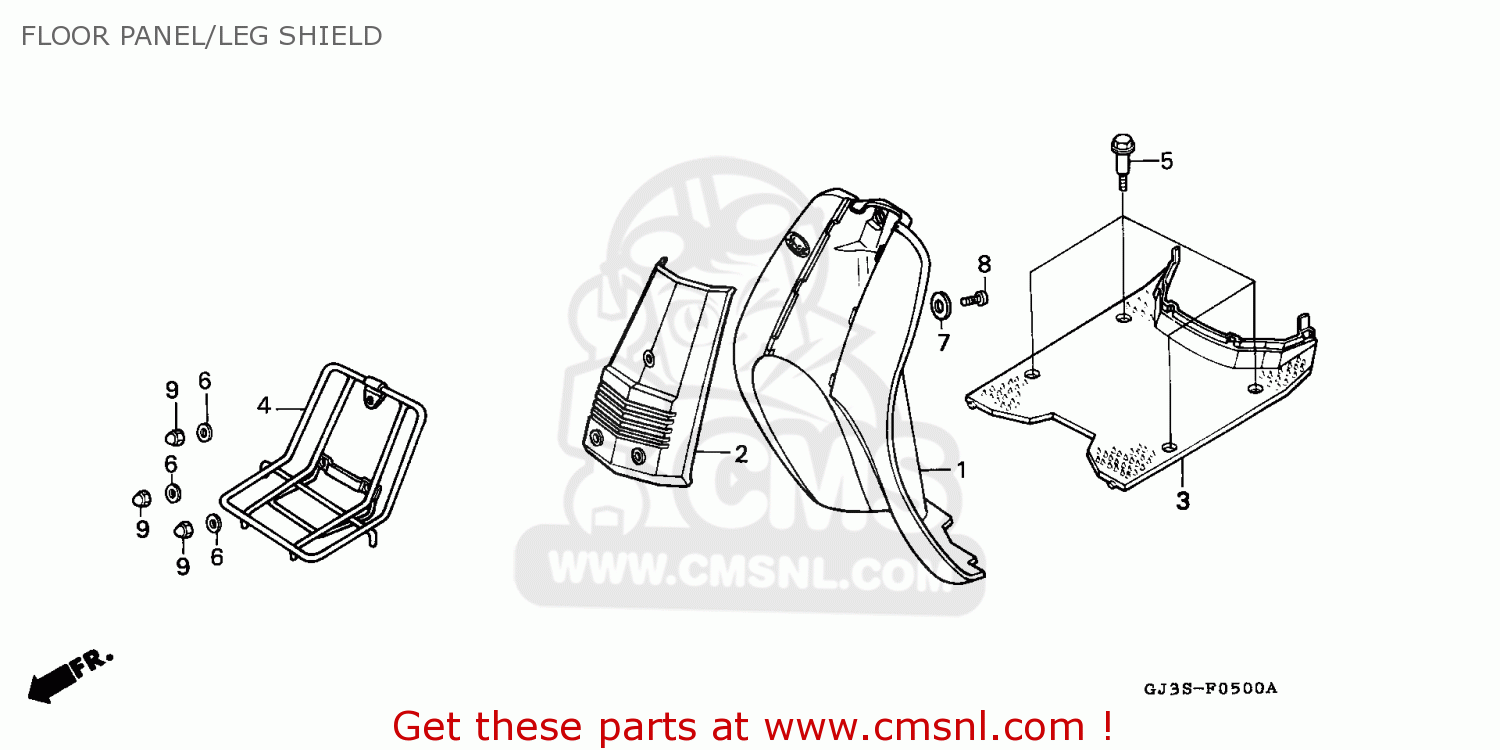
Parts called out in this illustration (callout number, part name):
1	SET,LEGSHI*TYPE1*
2	COVER,FRON*NH318*
3	PANEL FLOOR NH-212R
4	CARRIER,FR.
5	BOLT,FLANGE.6X27
6	WASHER, 6X17
7	WASHER,18MM
8	SCREW,PAN,6X12
9	NUT, BLIND, 6M/M
